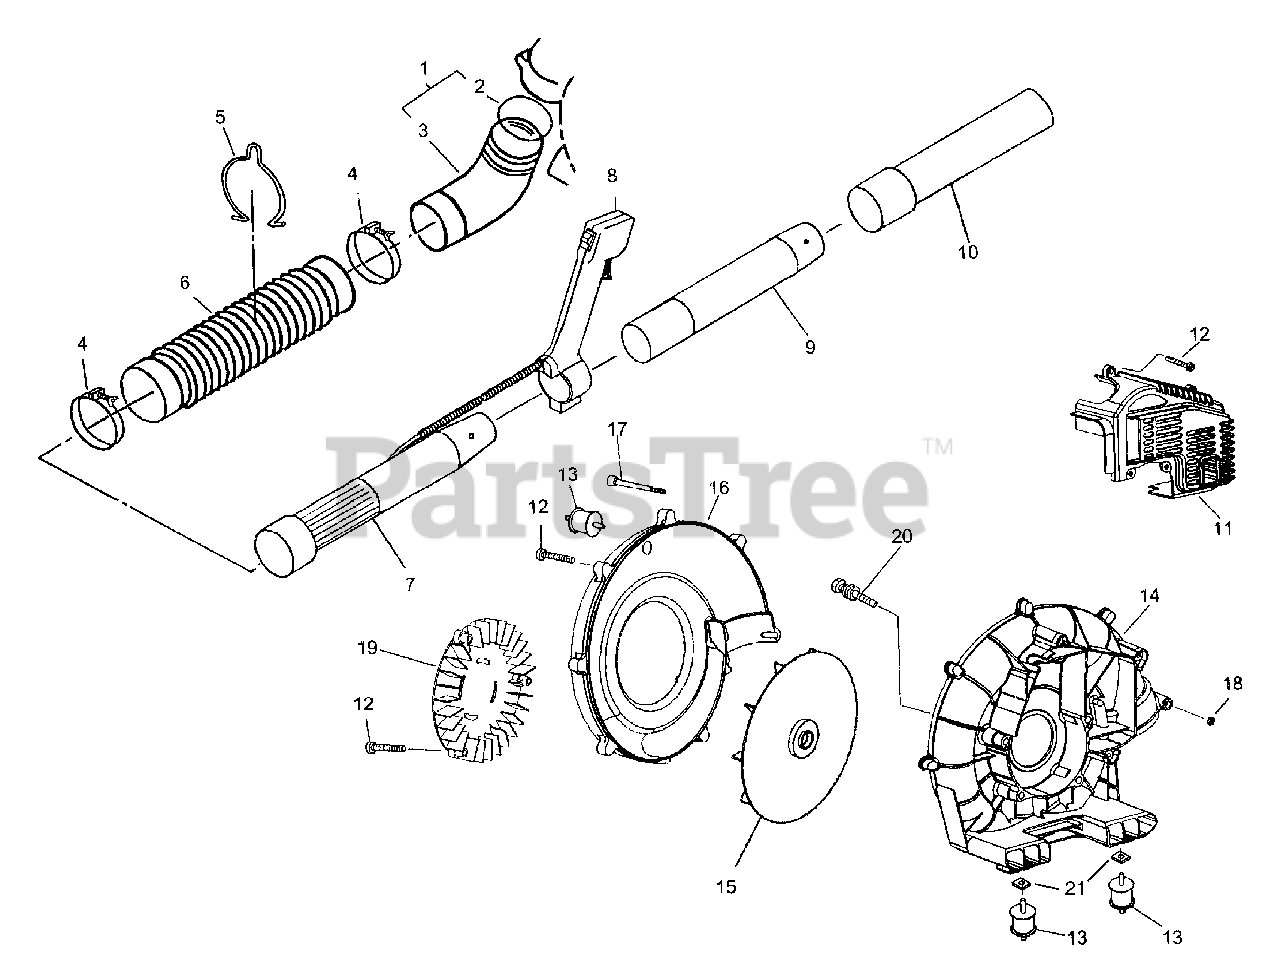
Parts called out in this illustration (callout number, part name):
1	ELBOW PIPE C.P.
2	O-RING
3	ELBOW PIPE
4	HOSE BAND
5	WIRE CLAMP
6	FLEX, PIPE
7	BASE PIPE
8	THROTTLE LEVER ASSY
9	MIDDLE PIPE
10	TUBE, END
11	COVER
12	TAPPING SCREW M5X20
13	VIBRO-ISOLATING RUBBER
14	FAN CASE
15	FAN
16	FAN CASE
17	SOCKET SCREW
18	NYLON NUT M5
19	FAN COVER
20	HEX BOLT
21	SQUARE NUT
